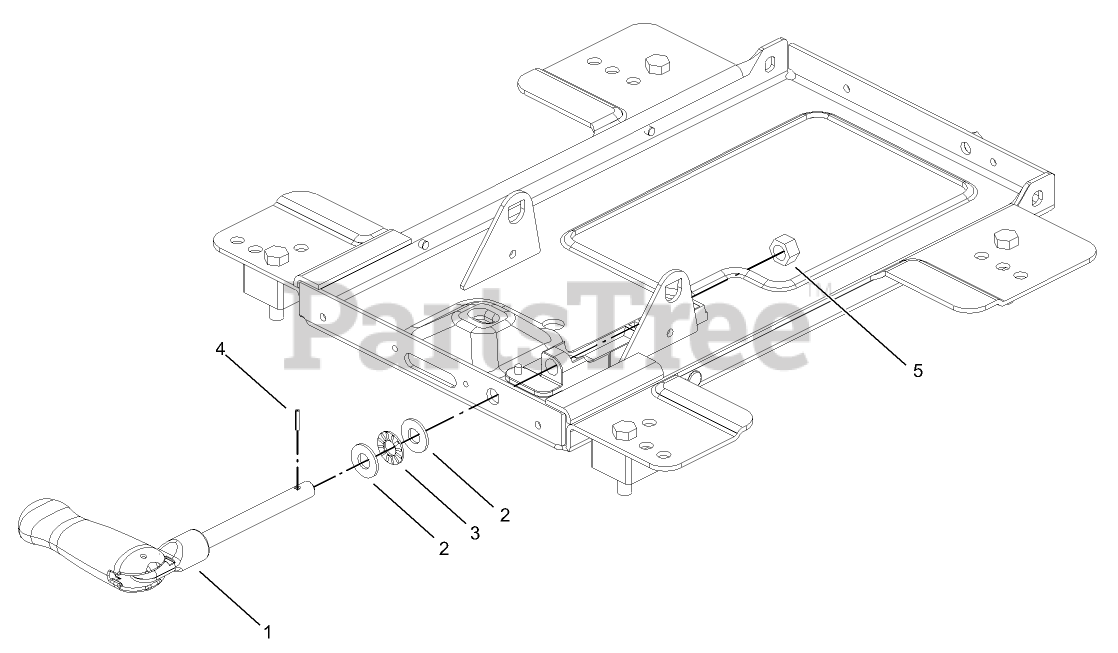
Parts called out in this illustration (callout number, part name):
1	Weight Adjust Handle ASM
2	Race-Thrust
3	Bearing-Thrust
4	Pin
5	Nut
